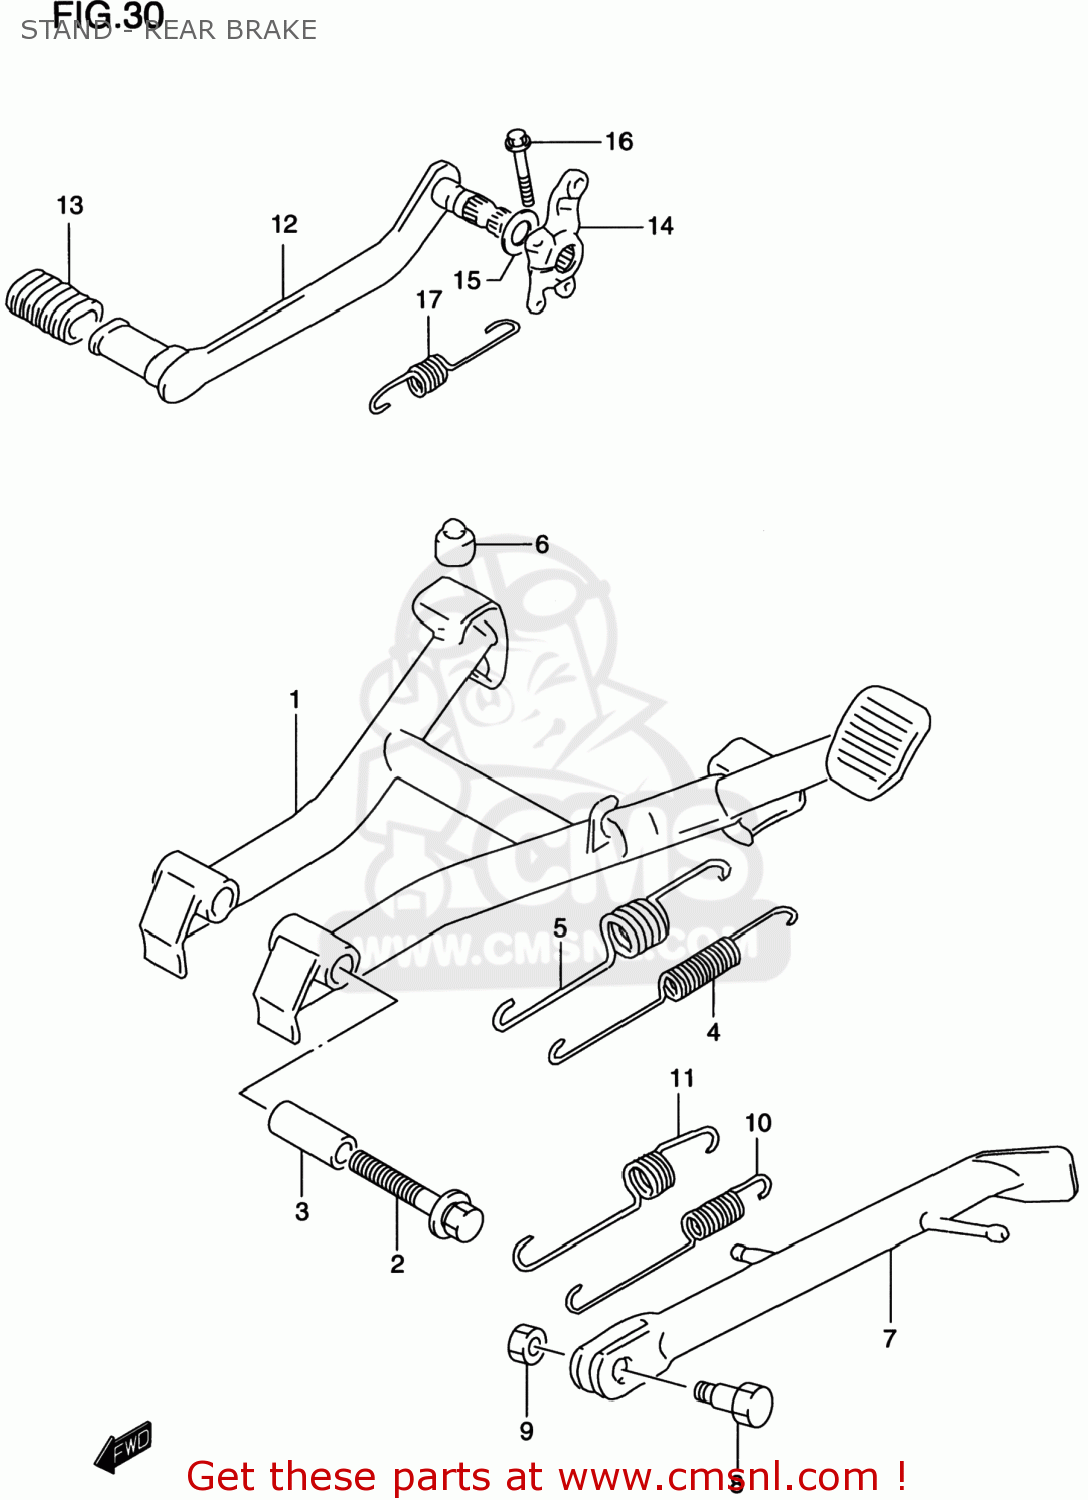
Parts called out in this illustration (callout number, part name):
1	STAND,CTR
2	BOLT
3	SPACER(10X16X38.8)
4	SPRING
5	SPRING OUTER
6	CUSHION
7	STAND,PROP(BLACK)
8	BOLT(10X34)
9	NUT
10	SPRING
11	SPRING
12	PEDAL,BRAKE
13	RUBBER,PEDAL
14	ARM,BRAKE ROD
15	WASHER,BRAKE PEDAL
16	BOLT
17	SPRING
